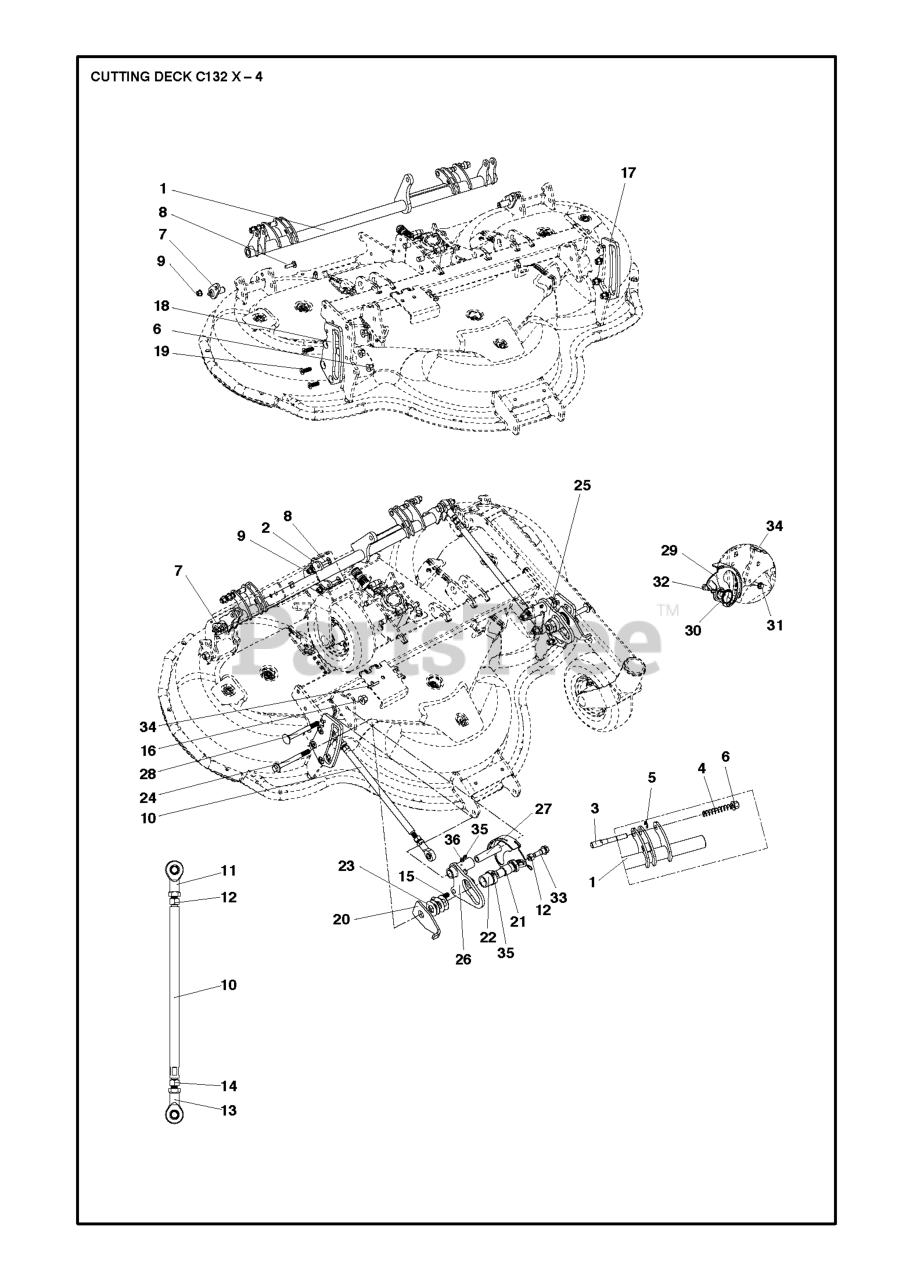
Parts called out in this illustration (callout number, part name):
9	NUT FLANGE
31	BOLT
35	GREASE NIPPLE
36	WASHER - M6
